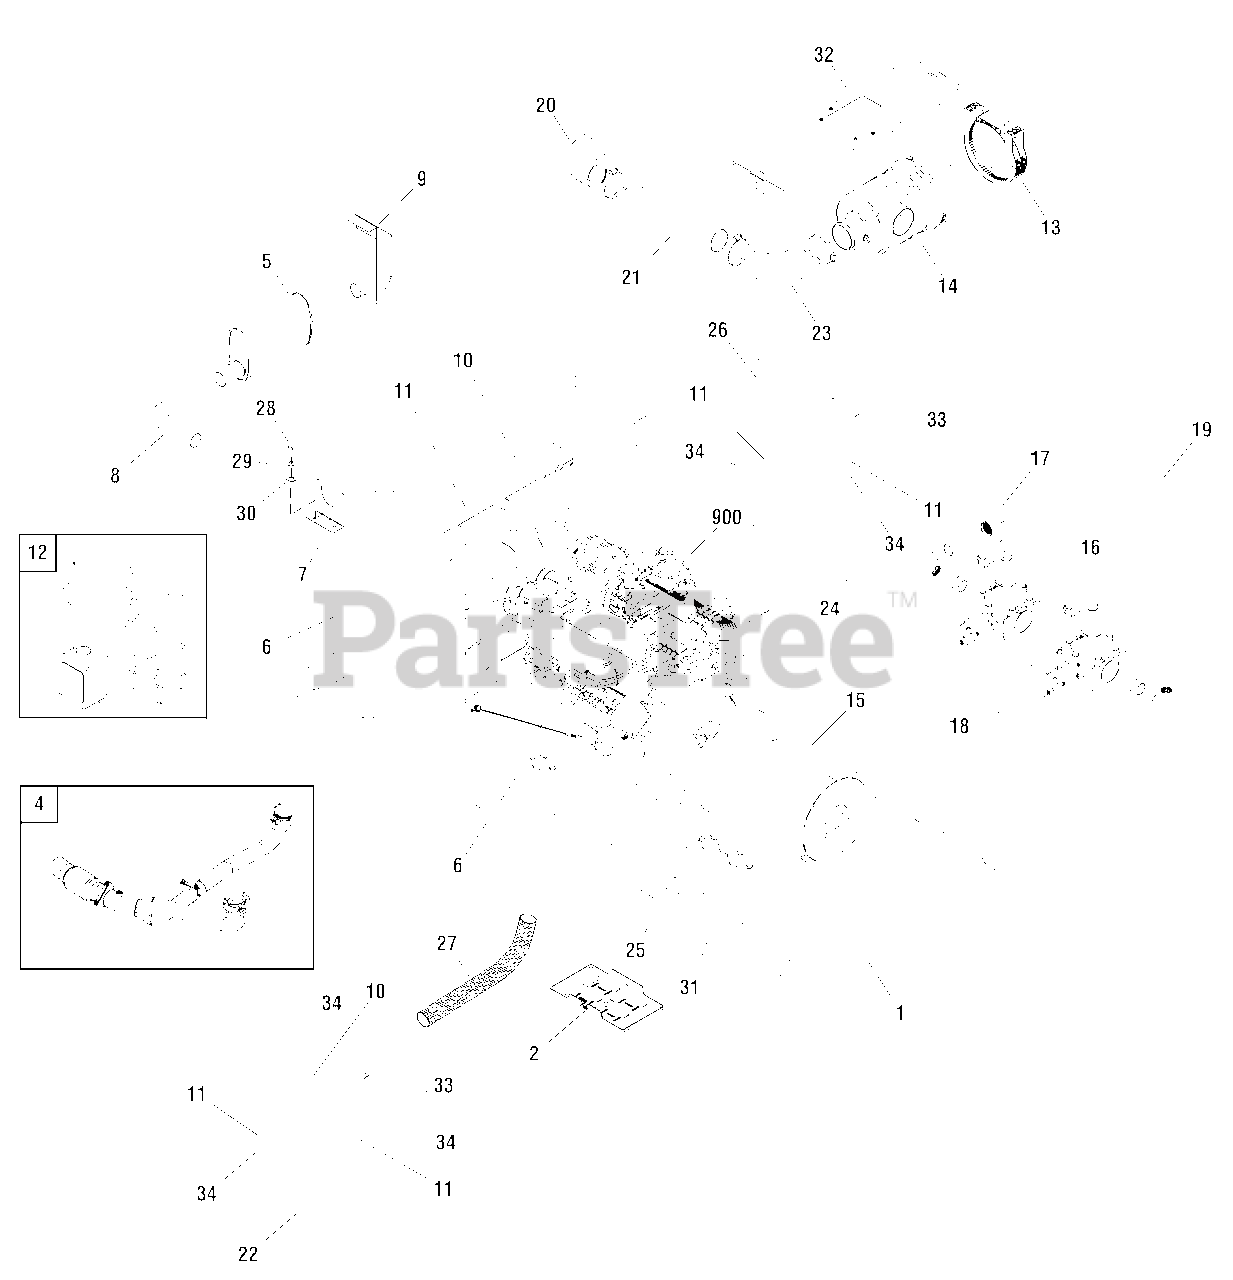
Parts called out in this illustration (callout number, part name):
1	BASE
4	KIT, Exhaust
5	MUFFLER
6	DECAL
7	BRACKET, Muffler
9	DIFFUSER
11	DECAL
12	BOTTLE, Overflow
24	DECAL
28	* CAPSCREW, Hex Head, 1/4-20 x 3/4
29	* WASHER, Lock, 1/4-M6
30	* WASHER, Flat, 1/4
31	MOUNT, Vibration
33	DECAL
34	DECAL
900	** ENGINE
